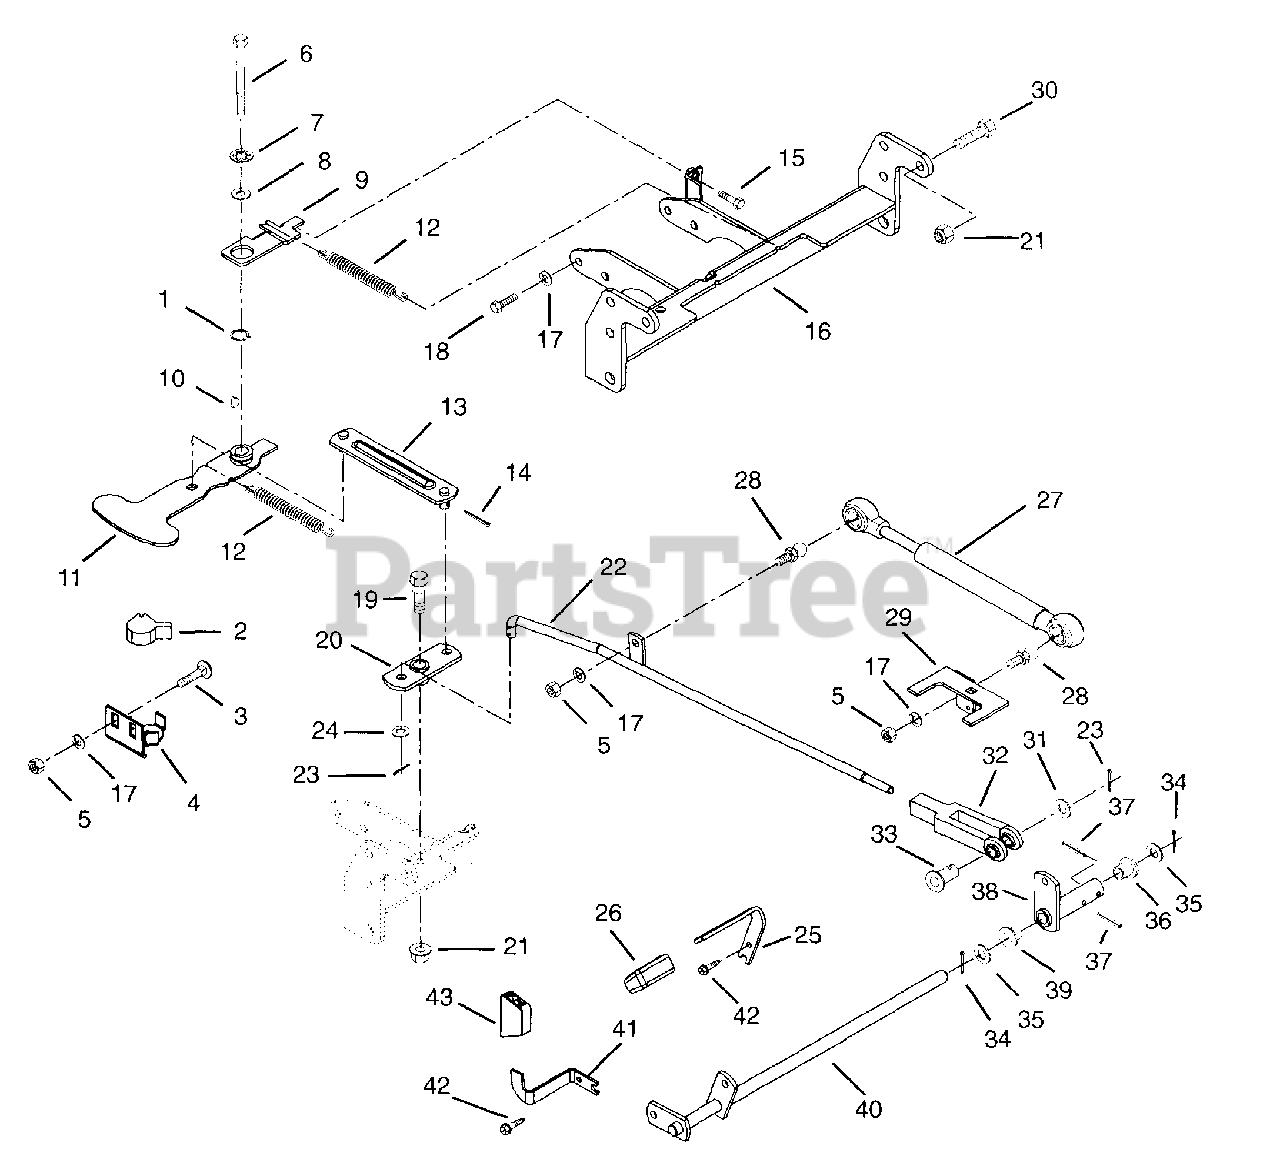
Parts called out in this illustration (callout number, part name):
1	RG-RTNG-EXT .875X.042
3	@BLT-RHDSSQNK .31-18X.62 G5YZ
4	MOUNT - MAGNET
5	@NUT-HEX .31-18 YWZC
6	@BLT-HEX .25-20X1.50 GR5 YWZC
7	@WSHR-LK-EXT.262X.502X.026YWZC
8	@WSHR-FL-STL.312X.734X.065 YWZ
9	ARM, NEUTRAL
10	KEY-WDRF .125X.500X.203 SAE 3
11	ARM, NEUTRAL CONTROL
12	SG-TENS .085X.60X5.13 WLD8.3
13	LINK, SHIFT
14	@PIN-CTR .12X.75 EXTPRSQCT YWZ
15	@BLT-HEX .31-18X.75 GR5 YWZC
16	MOUNT, TORQUE
17	WSHR-LK .312X.097 HVY YWZC
18	@BLT-HEX .31-18X.75 GR5 YWZC
19	BLT-SHLDR .38-16X1.25
20	BELLCRANK - SHIFT
21	@NUT-LK-CTR .38-16 YWZC
22	ROD - SHIFT
23	@PIN-CTR .09X.75 EXTPRSQCT YWZ
24	@WSHR-FL-STL.406X.812X.065 YWZ
25	PEDAL - FORWARD
26	COVER - PEDAL - FORWARD
27	DAMPER - HYDRAULIC
28	STUD- BALL
29	BRACE-DAMPER
30	@BLT-HEX .38-16X.75 GR5 YWZC
31	WSHR-FL-STL .390X.75X.125 YWZC
32	YOKE, .312-24 X 2.25
33	PIN-CLEV .312X.822 HDND PL
34	@PIN-CTR .12X1.00 EXTPRSQCT YZ
35	WSHR-FL-STL .52X.827X.062 YWZC
36	BSHG-FLG .515X.750X.745X1.00NY
37	PIN-GRV .188X1.25 TP A
38	ARM & HUB - SHIFT
39	BSHG-FLG .502X1X.750
40	SHAFT - PEDAL
41	PEDAL - REVERSE
42	@SCR-TAP .38-16X1.00 HWH TR YZ
43	COVER - PEDAL - REVERSE
